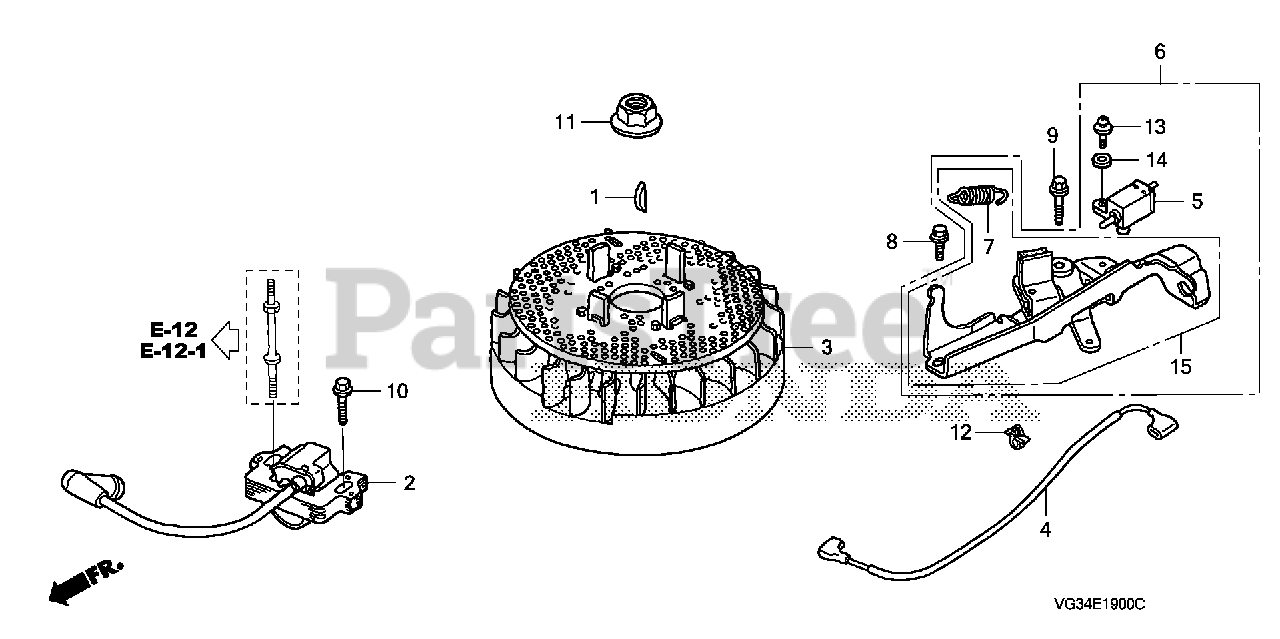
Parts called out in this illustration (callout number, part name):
1	KEY, SPECIAL WOODRUFF (25X18)
2	COIL ASSY., IGNITION (USE FOR F/W OF TEC) (TEC)
3	FLYWHEEL ASSY. (TEC) (USE FOR IGN. COIL OF TEC)
4	WIRE, STOP SWITCH
5	SWITCH ASSY., ENGINE STOP (N.C)
6	BRAKE ASSY.
7	SPRING, BRAKE LEVER
8	BOLT, FLANGE (6X14) (CT200)
9	BOLT, FLANGE (6X23) (CT200)
10	BOLT, FLANGE (6X20) (CT200)
11	NUT, SPECIAL (14MM)
12	CLIP A, CABLE (3.8MM BLACK) (NIFCO)
13	SCREW-WASHER (4X12)
14	WASHER, PLAIN (4MM)
